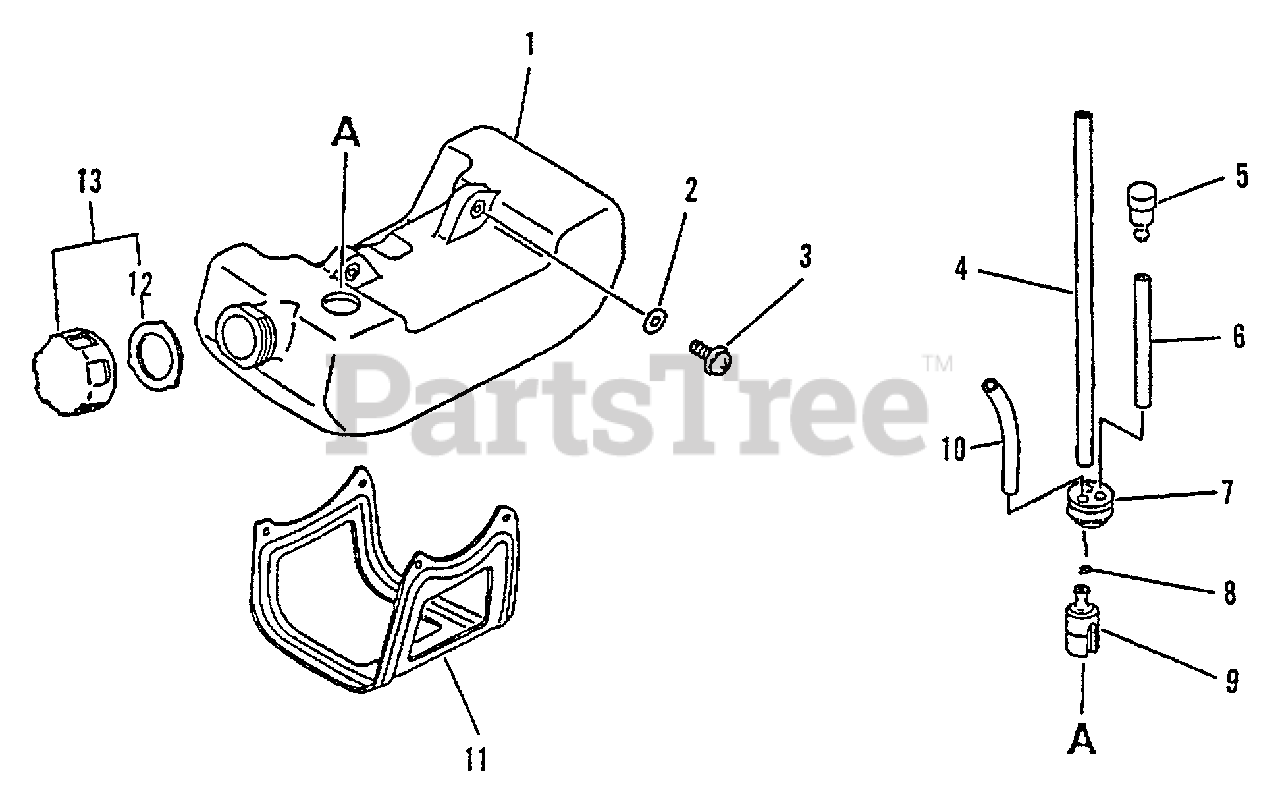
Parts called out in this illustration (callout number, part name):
1	TANK, FUEL
2	WASHER - 5
3	SCREW - 5X16
4	PIPE - 3X5X180 -- BLACK
5	VENT, FUEL TANK
6	PIPE - 3X5X70 -- BLACK
7	GROMMET
8	CLIP - 6
9	FILTER, FUEL
10	PIPE - 3X6X90 -- CLEAR
11	GUARD, FUEL TANK
12	GASKET, CAP
13	CAP ASSY
